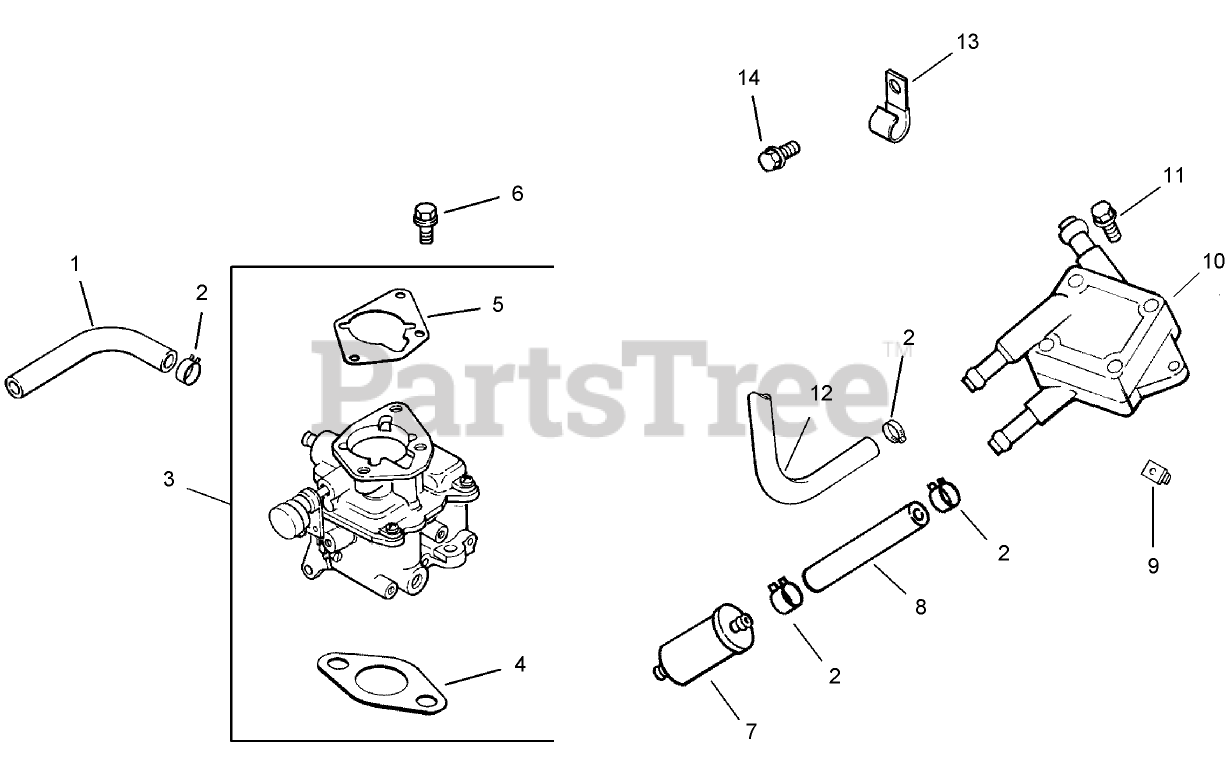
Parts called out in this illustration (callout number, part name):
1	Line-Fuel (9.5)
2	CLAMP-HOSE, SPRING (1/2)
3	Carburetor Kit w/gasket (Incl. Ref. 4-5)
4	Gasket-Carburetor
5	GASKET-BASE, AIR CLEANER
6	SCREW-FLANGE (M6X1.0X30)
7	FILTER-FUEL
8	Line-Fuel, 42mm
9	Nut-Plastic
10	PUMP-FUEL
11	SCREW-TAP (M6X1.7X18)
12	Line-Fuel, Flexible (15.5)
13	CLIP-CABLE
14	Screw-HF (M6x1.0x12)
